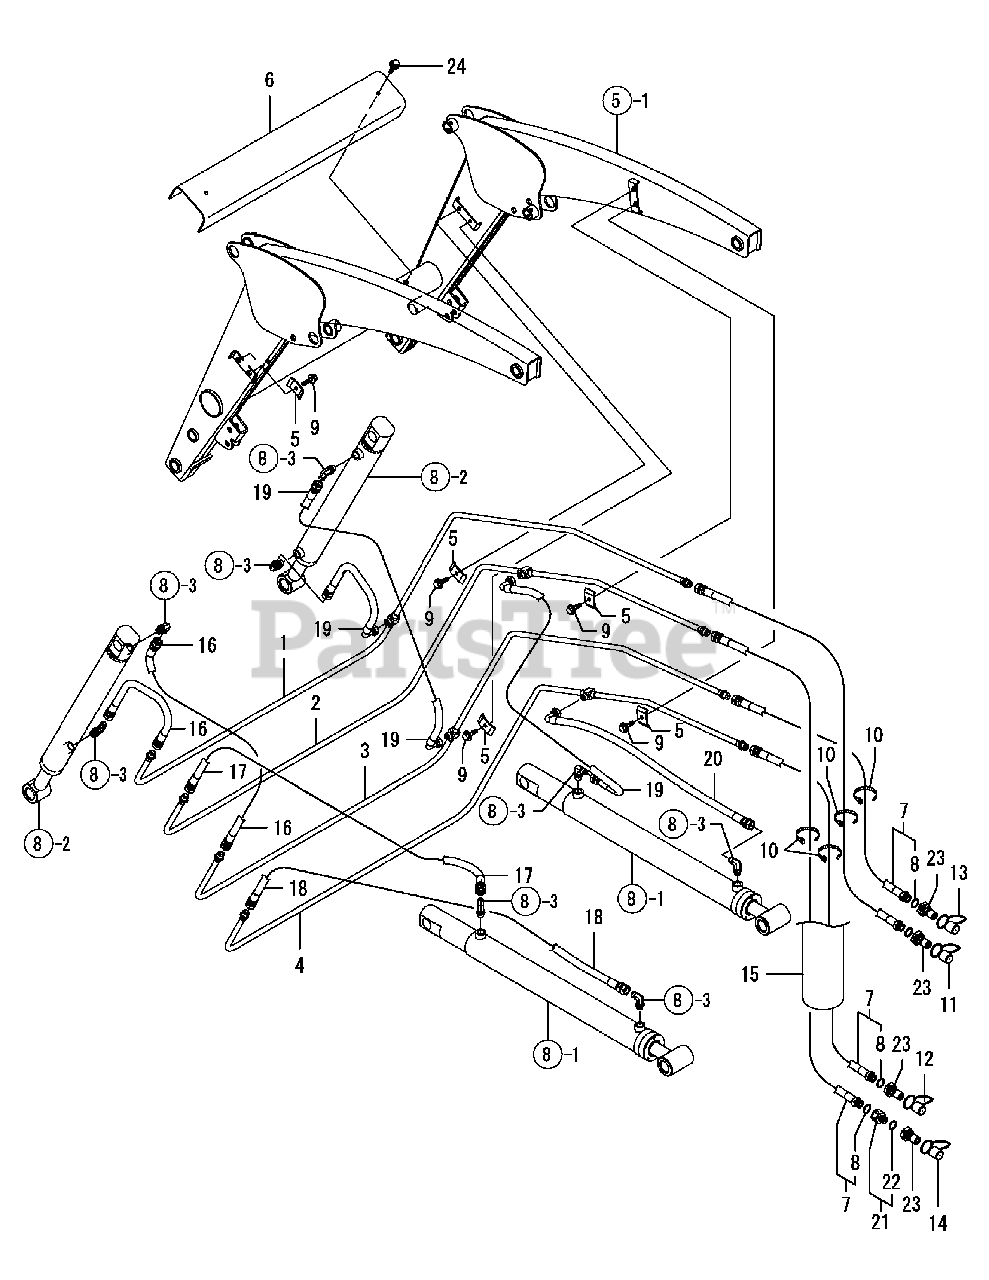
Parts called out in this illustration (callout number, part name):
1	HP PIPE, TILT CMP
2	HP PIPE, UP CMP
3	HP PIPE, DUMP CMP
4	HP PIPE, DOWN CMP
7	HP HOSE,INTAKE RED
11	DUST PLUG,M RED
12	DUST PLUG,M BLUE
13	DUST PLUG,M YELLOW
14	DUST PLUG,M GREEN
15	COVER,HOSE INTAKE
16	HP HOSE 3/8-500 CMP
17	HP HOSE 3/8-650 CMP
18	HP HOSE 3/8-1100 CMP
19	HP HOSE,R-F 500 CMP
20	HP HOSE,R-F 650 CMP
21	FITTING,ORIFICE
23	COUPLER,QUICK 3/8M
24	BOLT M 8X 16 PLATED
